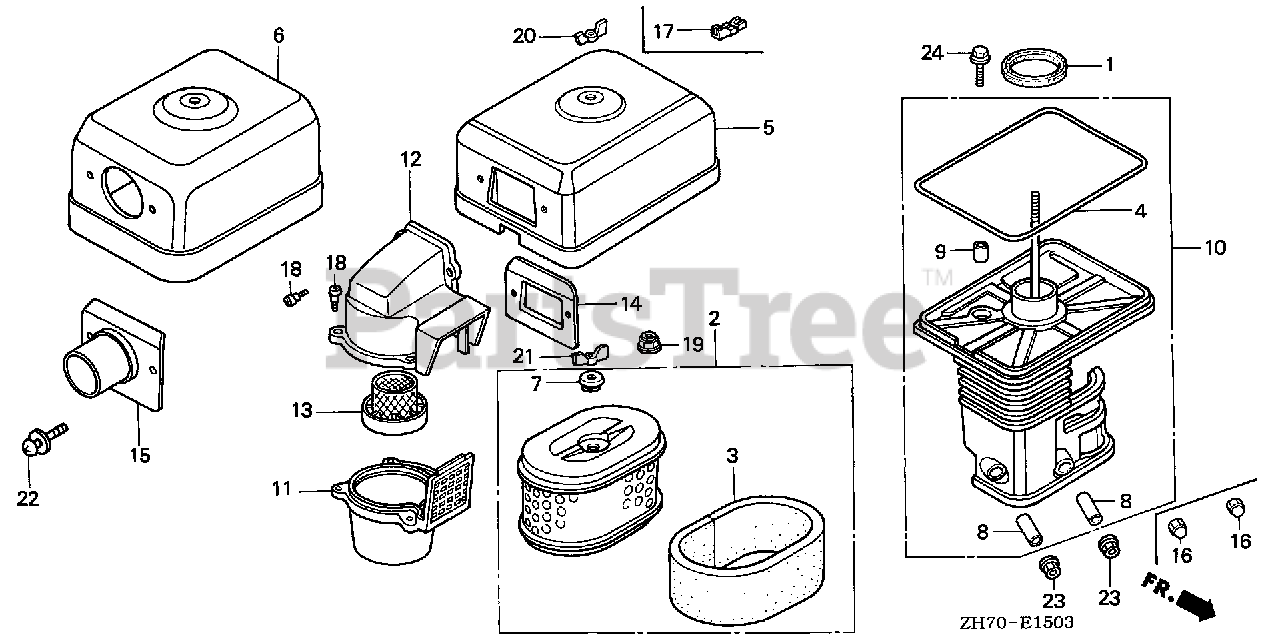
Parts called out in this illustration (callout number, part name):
1	GASKET, ELBOW
2	ELEMENT, AIR CLEANER (DUAL)
3	FILTER (OUTER)
4	GASKET, AIR CLEANER COVER
5	COVER, AIR CLEANER (CYCLONE)
7	GROMMET, AIR CLEANER
8	COLLAR, AIR CLEANER
9	COLLAR B, AIR CLEANER
10	ELBOW, AIR CLEANER
11	CASE, PRE AIR CLEANER
12	CAP, PRE AIR CLEANER
13	GUIDE, PRE AIR CLEANER
14	PLATE, PRE AIR CLEANER
16	NUT, CAP (6MM)
17	NUT, AIR CLEANER COVER (DACRO COATING)
17	WINGNUT (6MM) (BLACK)
18	BOLT, SPLASH GUARD
20	NUT, TOOL BOX SETTING
21	NUT, TOOL BOX SETTING
23	NUT, FLANGE (6MM)
24	BOLT, FLANGE (6X20)
